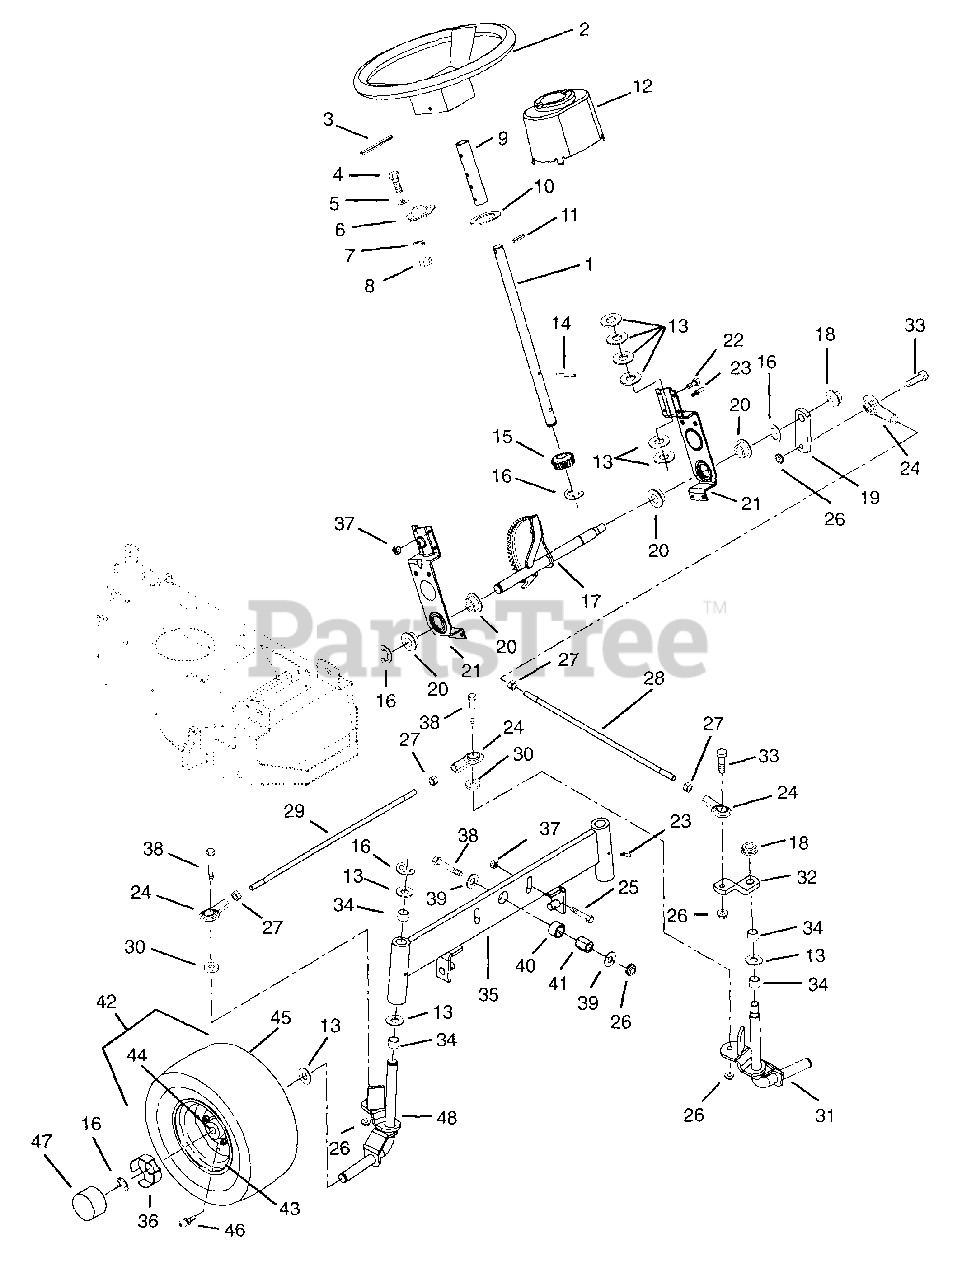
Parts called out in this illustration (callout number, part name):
1	COLUMN, STEERING
2	STEERING WHEEL 13"
3	PIN-ROLL .250X1.75
4	@BLT-HEX .31-18X.75 GR5 YWZC
5	@WSHR-FL-STL.312X.734X.065 YWZ
6	BRG-FLG .751X2 HOLESX.81
7	WSHR-LK .312X.097 HVY YWZC
8	@NUT-HEX .31-18 YWZC
9	TUBE .754 X .999 X 5.00
10	WSHR-FL-STL.754X1.125X.062YWZC
11	PIN-ROLL .250X1.000
12	CONE- STEERING COLUMN
13	WSHR-FL-STL.755X1.375X.062YWZC
14	PIN .249X1.125 DRIV-LOK SP
15	PINION GEAR-STEERING
16	RG-RTNG-EXT .750X.050
17	GEAR, STEERING
18	NUT-LK .563-18 GR5 YWZC
19	ARM, STEERING ROD
20	BSHG-FLG .750X1.093X.625X1.375
21	BRACKET, STEERING GEAR
22	@BLT-HEX .25-20X.75 GR5 YWZC
23	FTG-LUBE .25-28X.256 YWZC
24	ROD END, .38 RH
25	@BLT-HEX .38-16X1.25 GR5 YWZC
26	@NUT-LK-CTR .38-16 YWZC
27	NUT-JAM .375-24 YWZC
28	LINK - DRAG
29	ROD, TIE
30	BSHG-SLV .377X.624X.370
31	SPINDLE - LH
32	ARM - STEERING SPINDLE
33	BLT-BTHD .38-16X1.25 GR5
34	BSHG-SLV .750X.814X .750 BRZ
35	AXLE, FRONT
36	SPINDLE CUP
37	@NUT-LK-CTR .25-20 YWZC
38	@BLT-HEX .38-16X1.75 GR5 YWZC
39	WSHR-FL-STL .380X1.50X.125YWZC
40	BSHG-SLV .626X1.000X.524 HEX
41	BSHG-SLV .377X.623X.775 HEX
42	T/WHL ASSY 15X6.00-6
43	RIM
44	BSHG .75 BORE
46	FTG- LUBE .25-28X.97
47	HUB CAP
48	SPINDLE - RH
